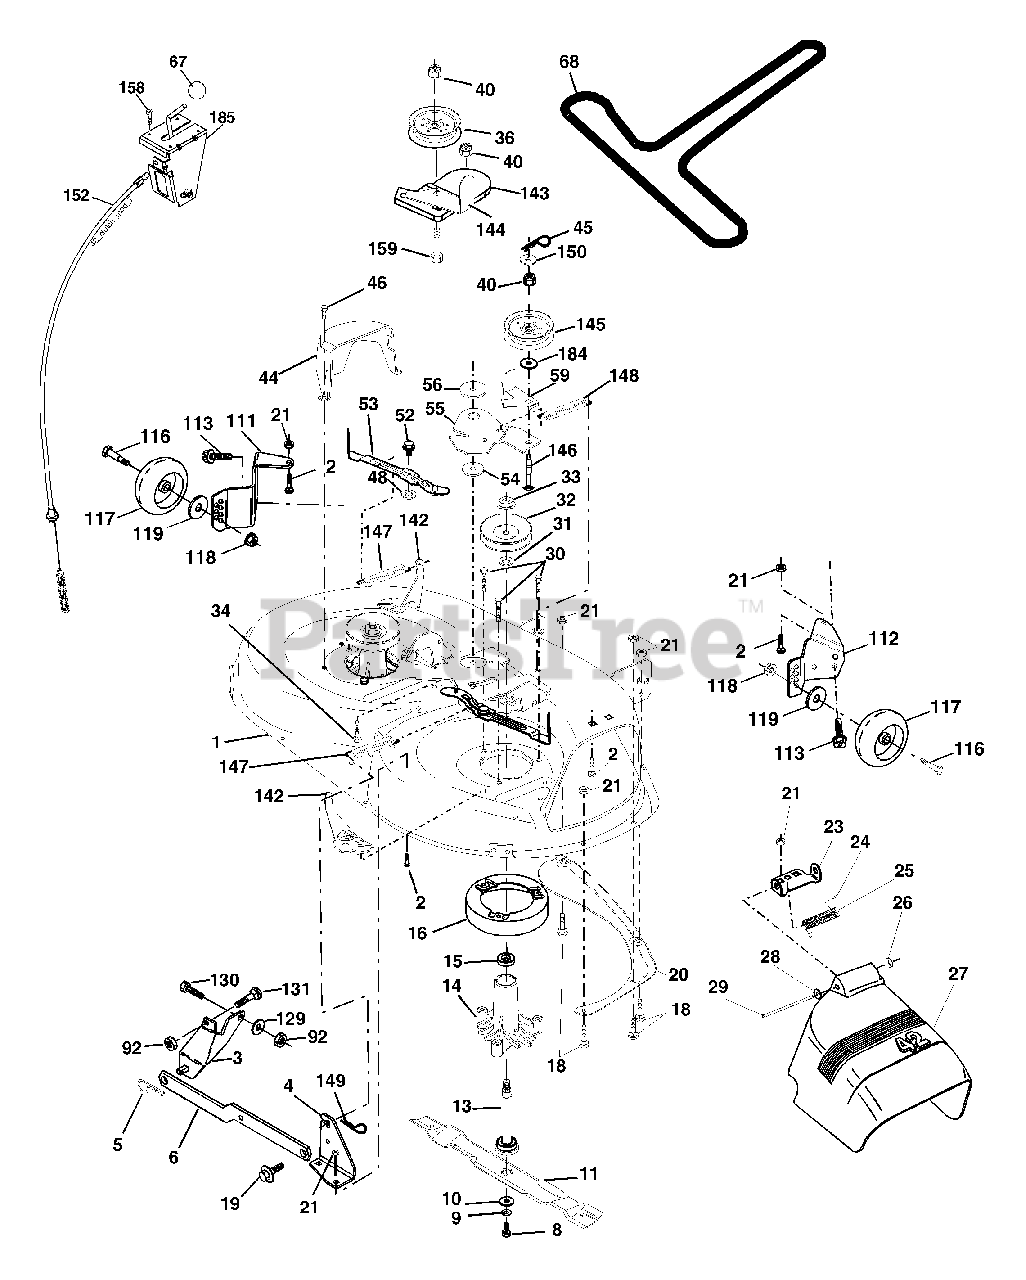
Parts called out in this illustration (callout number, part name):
1	Deck Asm MWR 42"weldment
2	Bolt Rdhd Sqnk 5/16-18 unc x 3/4
3	Bracket Asm Fr Sway Bar 38/42
4	Bracket Asm Deck 42"sway Bar
5	Retainer Spring
6	Deck Sway Bar
8	Bolt 3/8 - 24 x 1.25 Gr. 8
9	Washer Lock Hvy 3/8
10	Washer Hard Blade Mower Vented
11	Blade Mower 42"
11	Blade, 42" Mulching Premium
11	Blade, 42" Hi-Lift
13	Shaft Asm W/lower Bearing
14	Housing Mandrel Vented
15	Bearing Ball Mandrel
16	Stripper Mower
18	Bolt Rdhd Sqnk 5/16-18 x 5/8
19	Bolt Shoulder
20	Baffle Vortex 42
21	Nut Crownlock 5/16-18 unc
23	Bracket Deflector Mower 42"
24	Cap Sleeve 80 x 112 Blk Mower
25	Spring Torsion Deflector 2 52
26	Nut Push Phos & Oil
27	Shield Deflector Mower 42" Blk
28	Washer 11/32 x 5/8 x 16 Ga.
29	Rod Hinge 42" 6 75 Wlg
30	Screw Thd Rolling
31	Washer Spacer
32	Pulley Mandrel 42"
33	Nut Toplock Flng
34	Bolt Rdhd 3/8-16 unc x 1-1/2 Gr. 5
36	Pulley Idler Flat
37	Washer 13/32 x 13/16 x 16
40	Nut Lock 3/8-16 unc
44	Guard Mandrel LH Black
45	Spring Retainer 1" Zinc/cad
46	Screw Hex Thd Cut 1/4-20 x 5/8 T
48	Washer Hardened Smaller
52	Bolt Shoulder 5/16-18 unc Blkz
53	Arm Asm Pad Brake
54	Washer Hardened
55	Arm Idler 42"mower LT/YT
56	Spacer Retainer Mower
59	Guard TUV Idler
67	Knob Rd 3/8-16 Plstc Thds Blk
68	V-Belt Mower 42"
92	Nut 3/8-16 unc
111	Bracket Wheel Guage LH
112	Bracket Wheel Guage RH
113	Bolt 5/16-18 Hex Whs-Hd Lck Ser.
116	Bolt Shoulder
117	Wheel Guage
118	Nut Lock 3/8-16 unc
119	Washer 3/8 x 7/8 x 14 Ga.
129	Washer 13/32 x 13/16 x 12 Ga.
130	Bolt 3/8-16 x 1 Gr. 5
131	Bolt 3/8-16 x 1
142	Arm Spring Brake Mower
143	Bracket Arm Idler 42"
144	Keeper Belt 42" Clutch
145	Pulley Idler Flat
146	Bolt Carriage Idler
147	Spring Extension
148	Spring Return Idler
149	Retainer Spring Yellow
150	Washer 9/32 x 3/4 x 16 Ga.
152	Clutch Cable 42"
158	Screw Hex Thd Cut 1/4-20 x 1/2
159	Bolt Rdhd Sqn 3/8-16 unc x 1-3/4
184	Washer 13/32 x 7/8 x 10 Ga.
185	Head Asm. Cable Clutch
